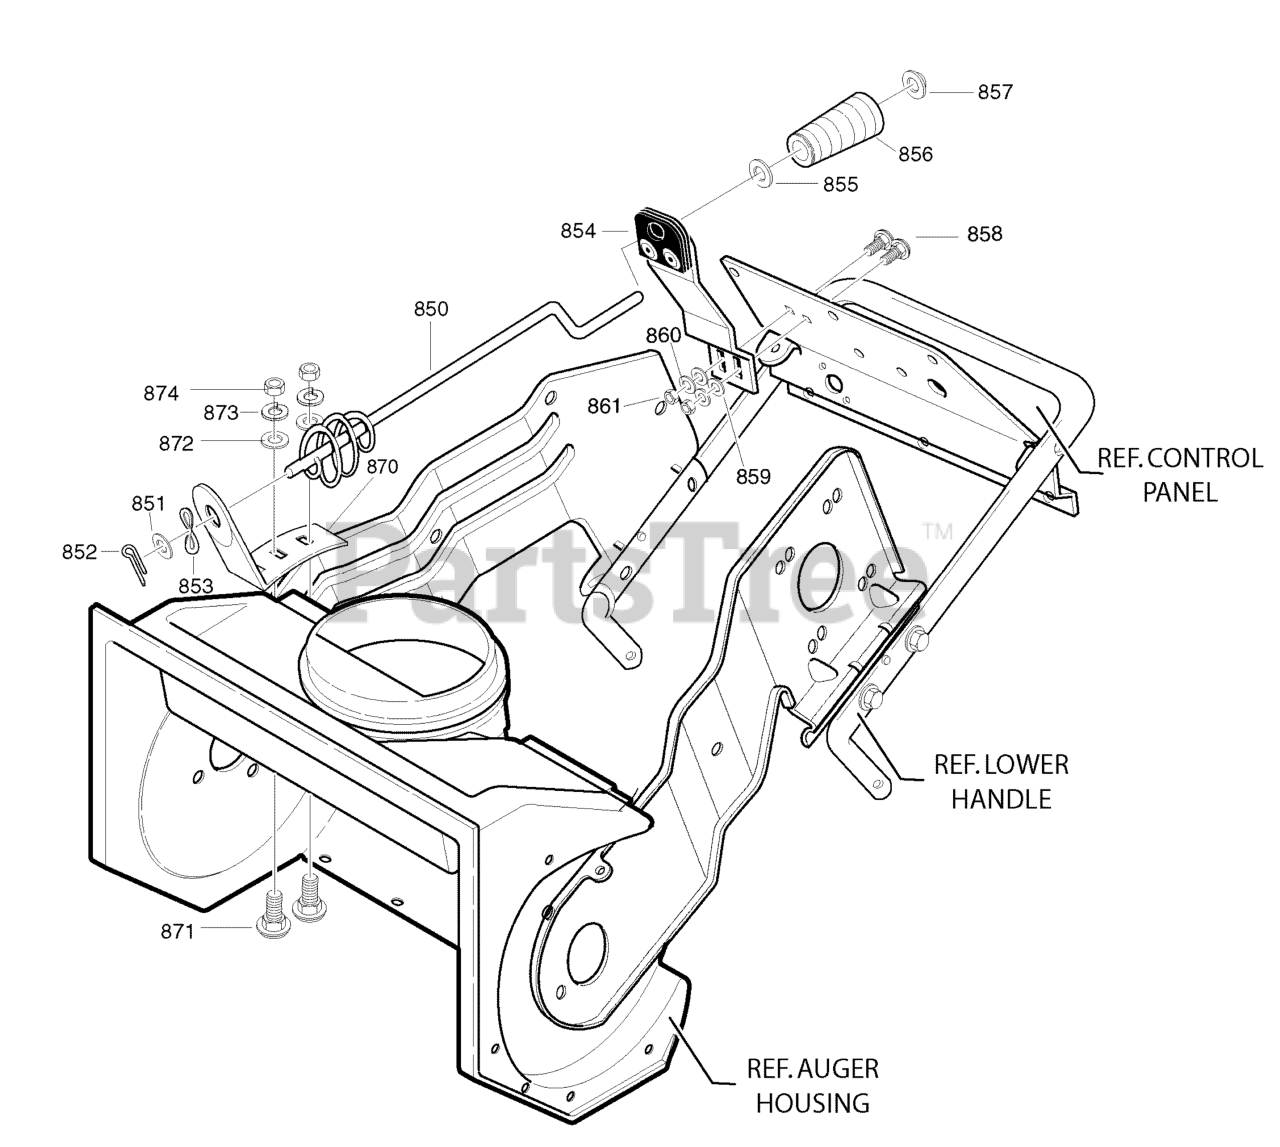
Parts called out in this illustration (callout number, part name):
850	ROD, CHUTE
851	WASHER, Flat, 13/32
852	PIN, COTTER
853	WASHER CURVED
854	ASSY, CHUTE CRANK
855	WASHER, Flat, 13/32
856	KNOB, SLEEVE
857	NUT, PUSH
858	BOLT, 1/4-20 X .63 CARRIAGE
859	WASHER, FLAT .344 X .69 X .065
860	WASHER, .31 X .58 X .08
861	NUT, 1/4-20 REGHEX
870	BRKT, CHUTE ROTATE
871	BOLT, 5/16-18 X .75 CARRIAGE
872	WASHER, FLAT .349 X .69 X .066
873	WASHER, SPLIT LOCK .31 X .58 X .08
874	NUT, 5/16-18 HEXHEAD
